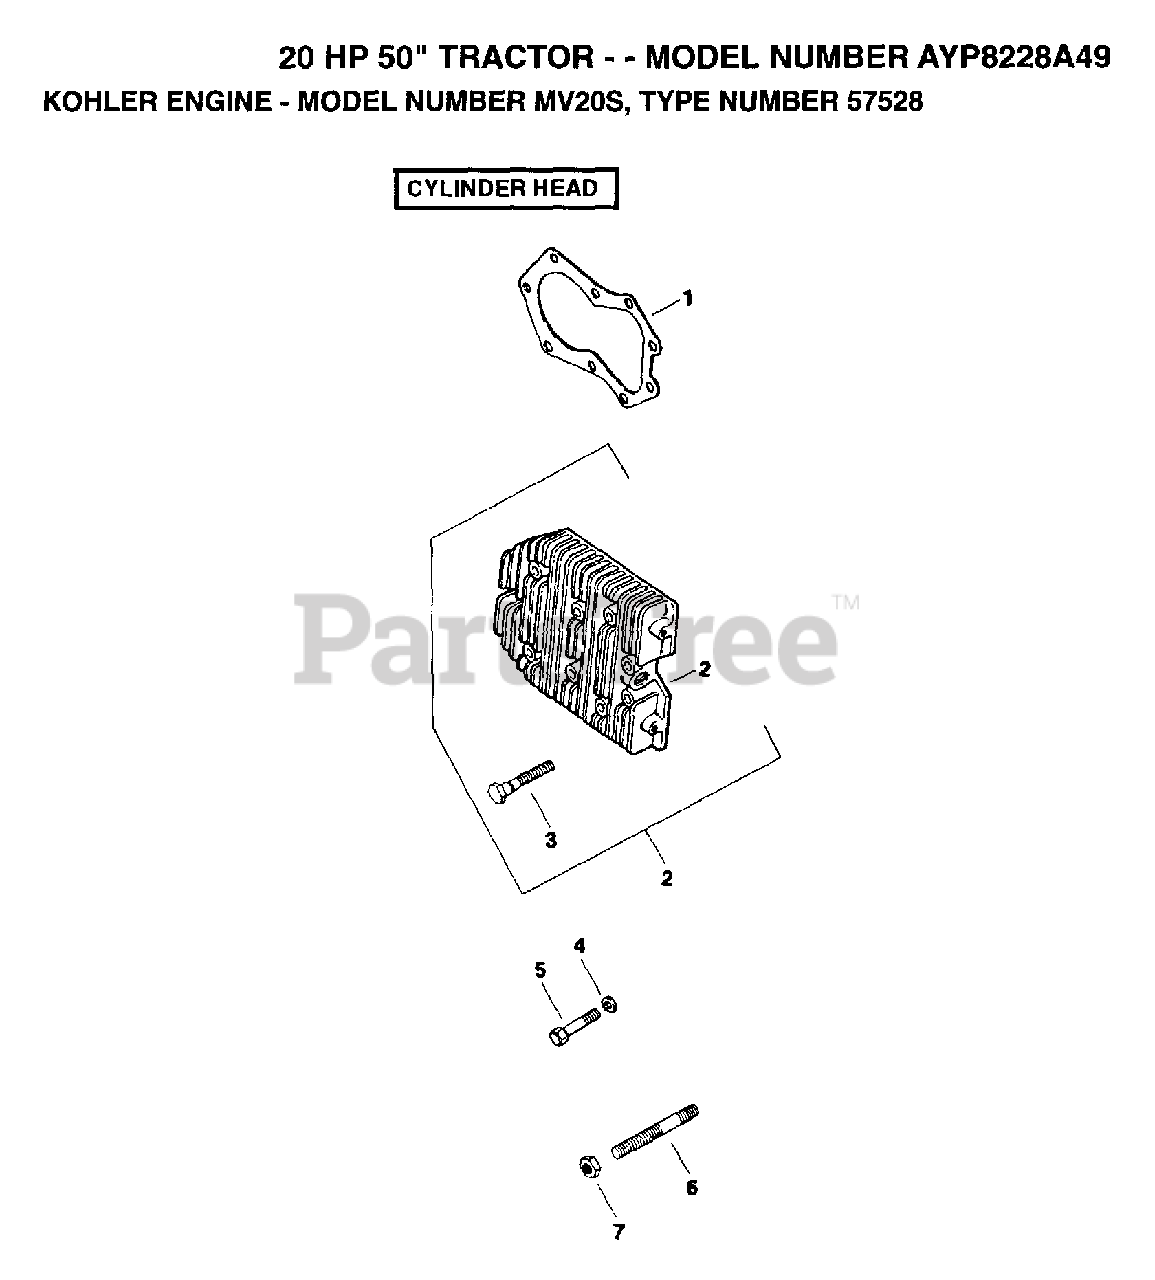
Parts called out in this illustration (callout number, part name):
2	KIT, CYL. HEAD
4	WASHER
7	NUT
